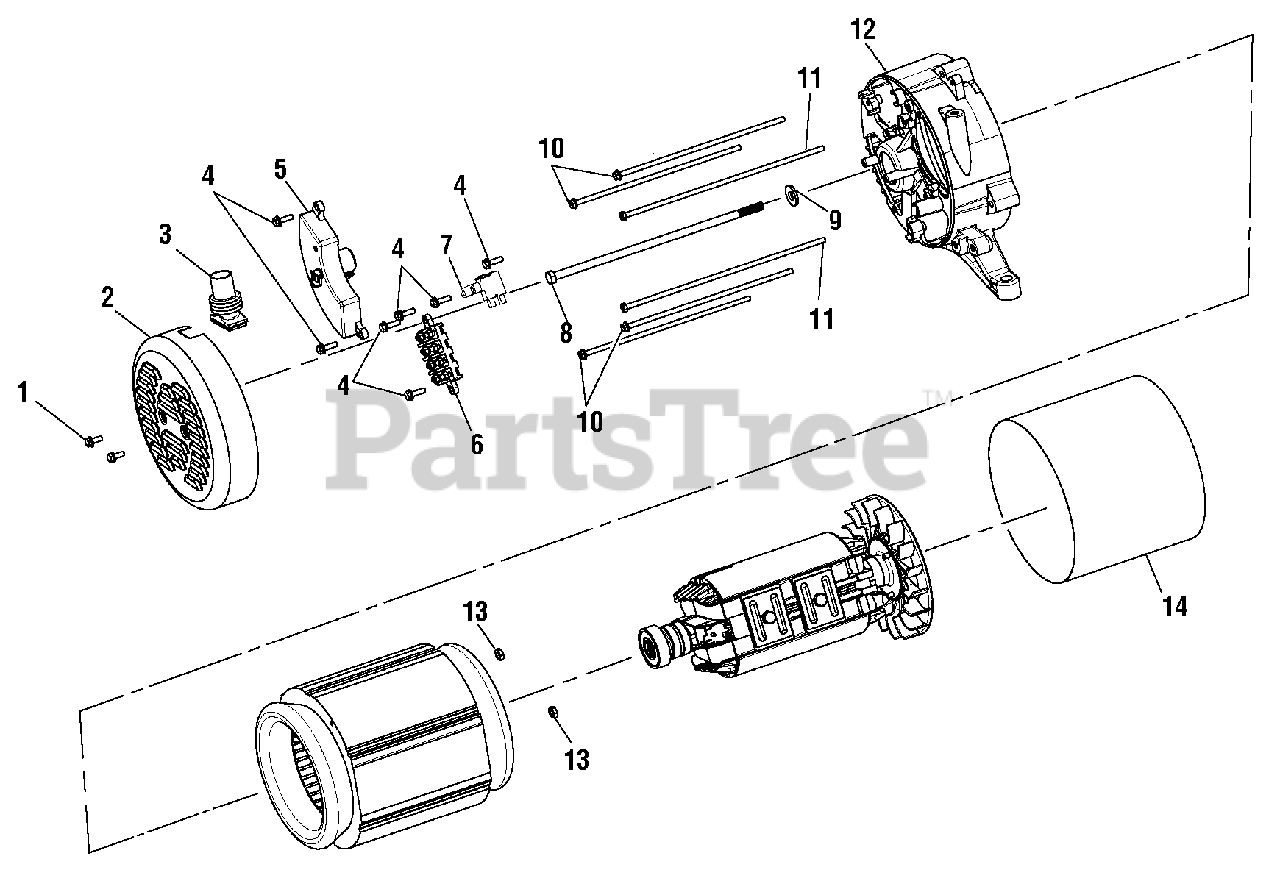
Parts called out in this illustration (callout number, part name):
1	Bolt (M5 x 10 mm, Hex Hd.)
2	Brush Cover
3	Rubber Boot
4	Bolt (M5 x 16 mm, Hex Hd.)
5	Automatic Voltage Regulator
6	Terminal Block
7	Brush Assembly Kit
8	Rotor Bolt (M12.7 x 242 mm, Hex Hd.)
9	Washer (5/16 in.)
10	Stator Bolt (1/4-20 x 7.5 in.)
11	Bolt (M5 x 230 mm, Hex Hd.)
12	Bearing Housing
13	Hex Nut (M5)
14	Generator Head Cover
